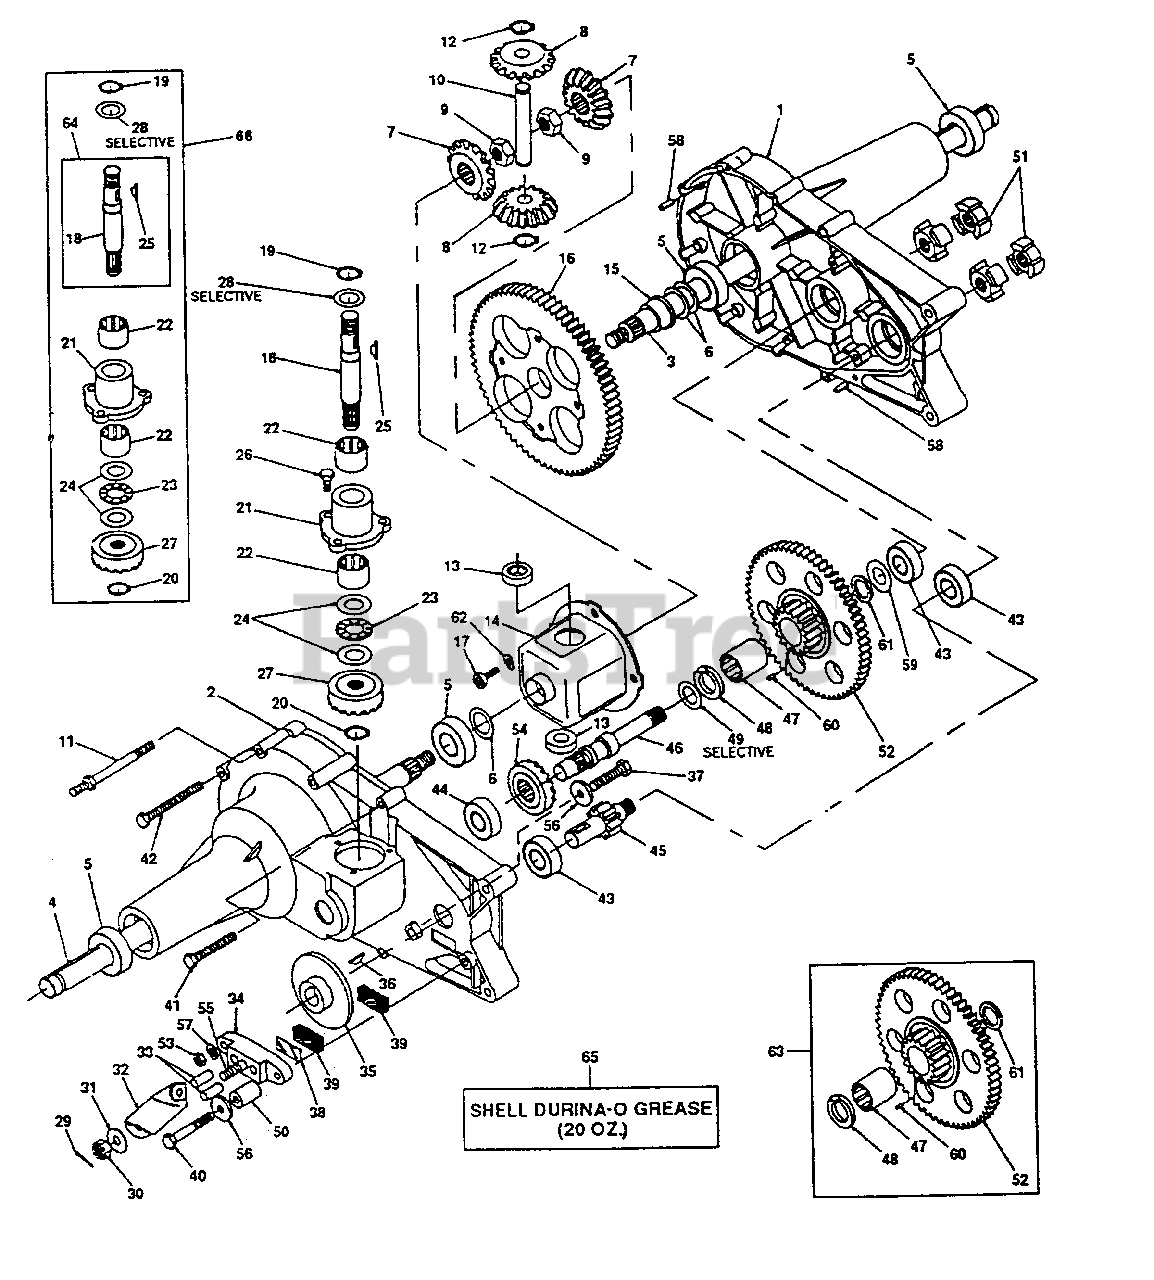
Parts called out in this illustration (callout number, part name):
1	Housing, Half L.H.
2	Housing, Half R.H.
5	Bearing, Ball
6	Washer, Flat 3/4 x 1-1/8 x .030
7	Gear, Miter
8	Gear, Miter
9	Nut, Hex Jam w/Patch 1/2-20
11	Screw, Stud
13	Bearing, Thrust
14	Housing Assembly, Differential
15	Bearing, Flange
16	Gear, Differential 72 Tooth
17	Bolt, Torx Head 1/4-28 x 5/8"
18	Shaft, Input
20	Retaining Ring 7/16"
21	Housing, Input Bearing
22	Bearing, Needle
23	Bearing, Thrust
24	Washer, Flat 5/8 x 1-1/8 x .030
25	Key, Hi-Pro 3/32 x 5/8
26	Screw, Hex W/Patch 1/4-20 x 3/4
27	Gear, Input Pinion 17 Tooth
28	Washer, Flat .62 x 1 x .05
30	Nut, Castle 5/16-24
31	Washer, Flat .343 x .88 x .062
32	Arm, Brake Actuator
33	Pin, Brake Actuating
34	Brake, Yoke
36	Key, Hi-Pro 3/16 x 5/8"
37	Screw, Hex 1/4-20 x 1.50
39	Puck, Brake
40	Screw, Hex w/Patch 1/4-20 x 2.00
41	Screw, Hex Self-Tap 1/4-20 x 2.00
42	Screw, Hex Self-Tap 1/4-20 x 3.00
43	Bearing, Ball
44	Bearing, Ball
45	Shaft, Pinion W/11 Tooth Gear
47	Bearing, Needle
48	Bronze Thrust Brg. 5/8 x 1-1/4 x 7/64
49	Washer, Flat .62 x 1.0 x .050
52	Gear, 60 and 17 Tooth
53	Nut, Hex 1/4-20
54	Gear, Drive Pinion 17 Tooth
55	Bolt, Square Head
56	Washer 15/16 x .265 x .125
57	Washer, Spring Lock 1/4"
58	Pin, Roll 3/16" x 1/2"
59	Washer, Flat .62 x 1.0 x .030
60	Pin, Dowel 3/32 x 1/4
62	Washer, Head Spring Lock 1/4"
63	Assembly, Gear, Reduction
64	Assembly, Shaft, Input
65	Shell Durina-O Grease (20 oz.)
66	Kit, Input Shaft
